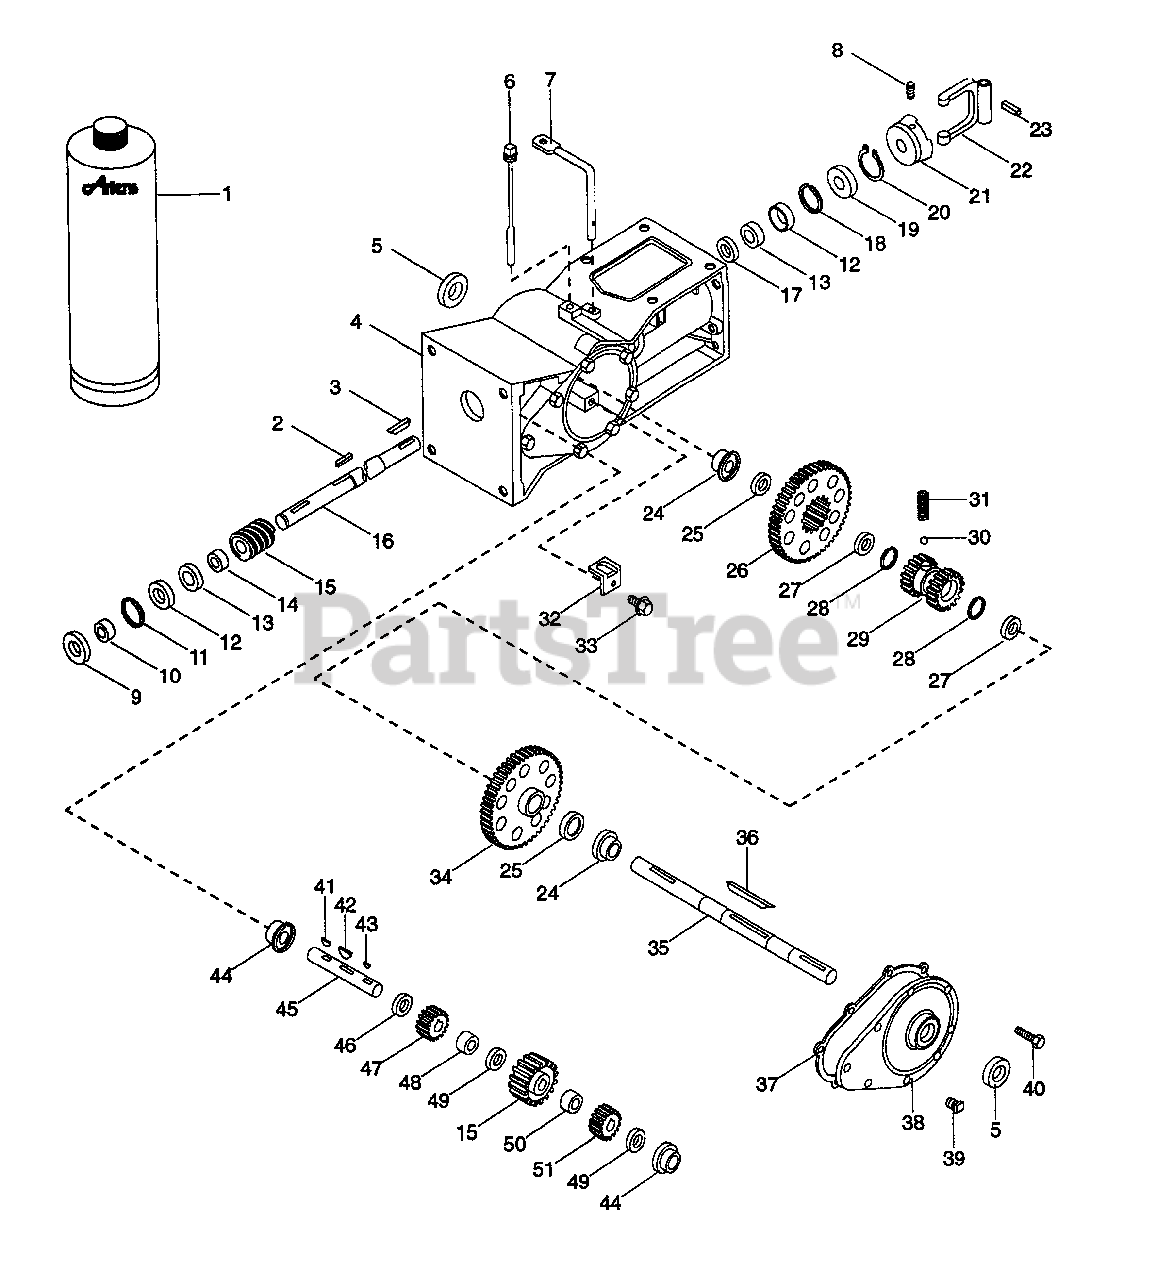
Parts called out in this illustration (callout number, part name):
1	ARIENS 16 OZ.BOTTLE OF L2 LUBE
2	KEY-SQ .188X1.0X.188 SAE 8630
3	KEY-FTHR .188X1.25X.187 SAE
4	TRANSMISSION HOUSING
5	SEAL 1.000X1.785X.250
6	DIP STICK
7	HIGH-LOW SHIFT LEVER
8	SCR-SET .32-18X.38 SKHCUPNL OH
9	SEAL 1.000X1.785X.250
10	SPACER BUSHING .99 X .75 X .50
11	RG-RTNG-INT 1.781X.052
12	BRG-CUP 1.781X.475
13	BRG-CONE .750X.61
14	BSHG, SPCR .755X1.12X.50 PM
15	WORM AND WORM GEAR
16	WORM SHAFT
17	WSHR-FL-STL .755X1.375X.125
18	RG-RTNG-INT 1.781X.052
19	SEAL .750X1.781X.250
20	RG-RTNG-EXT .750X.078
21	TILLER DRIVING JAW
22	SHIFT YOKE
23	PIN-ROLL .250X1.00
24	BSHG-FLG 1.000X1.25X1.000X1.50
25	WSHR-HRD-THRS 1.007X1.542X.062
26	HIGH GEAR
26	HIGH GEAR ASSY
27	SHIM
28	RG-RTNG-EXT 1.00X.078
29	CLUTCH HUB
30	STEEL BALL
31	SG-COMP .047X.31X.593 WLD11
32	RETAINER CLIP
33	SCR-TAP 10-24X.75 HWH PL TR
34	LOW GEAR
35	AXLE SHAFT
36	KEY-FTHR .25X2.75X.25 SAE1035
38	TRANSMISSION COVER
39	PIPE PLUG
40	SCR-TAP .312-18X1.0 HWH PL TR
41	KEY-WDRF .188X.75X.313 SAE 9
41	KEY-WDRF .188X.625X.31 SAE9MOD
42	KEY-WDRF .25X.687X.375
43	KEY-WDRF .188X.75X.313 SAE 9
44	BSHG-FLG .750X1.000X.750X1.250
45	PINION SHAFT
45	SHAFT, PINION
46	WSHR-HDND-THRST .760X1.25X.094
47	HIGH PINION
48	SPACER 1.13 X .75 X 1.64
48	SPACER 1.25 X .75 X .75
49	WSHR-HDND-THRST .758X1.23X.031
50	SPACER 1.25 X .75 X .75
51	LOW PINION
